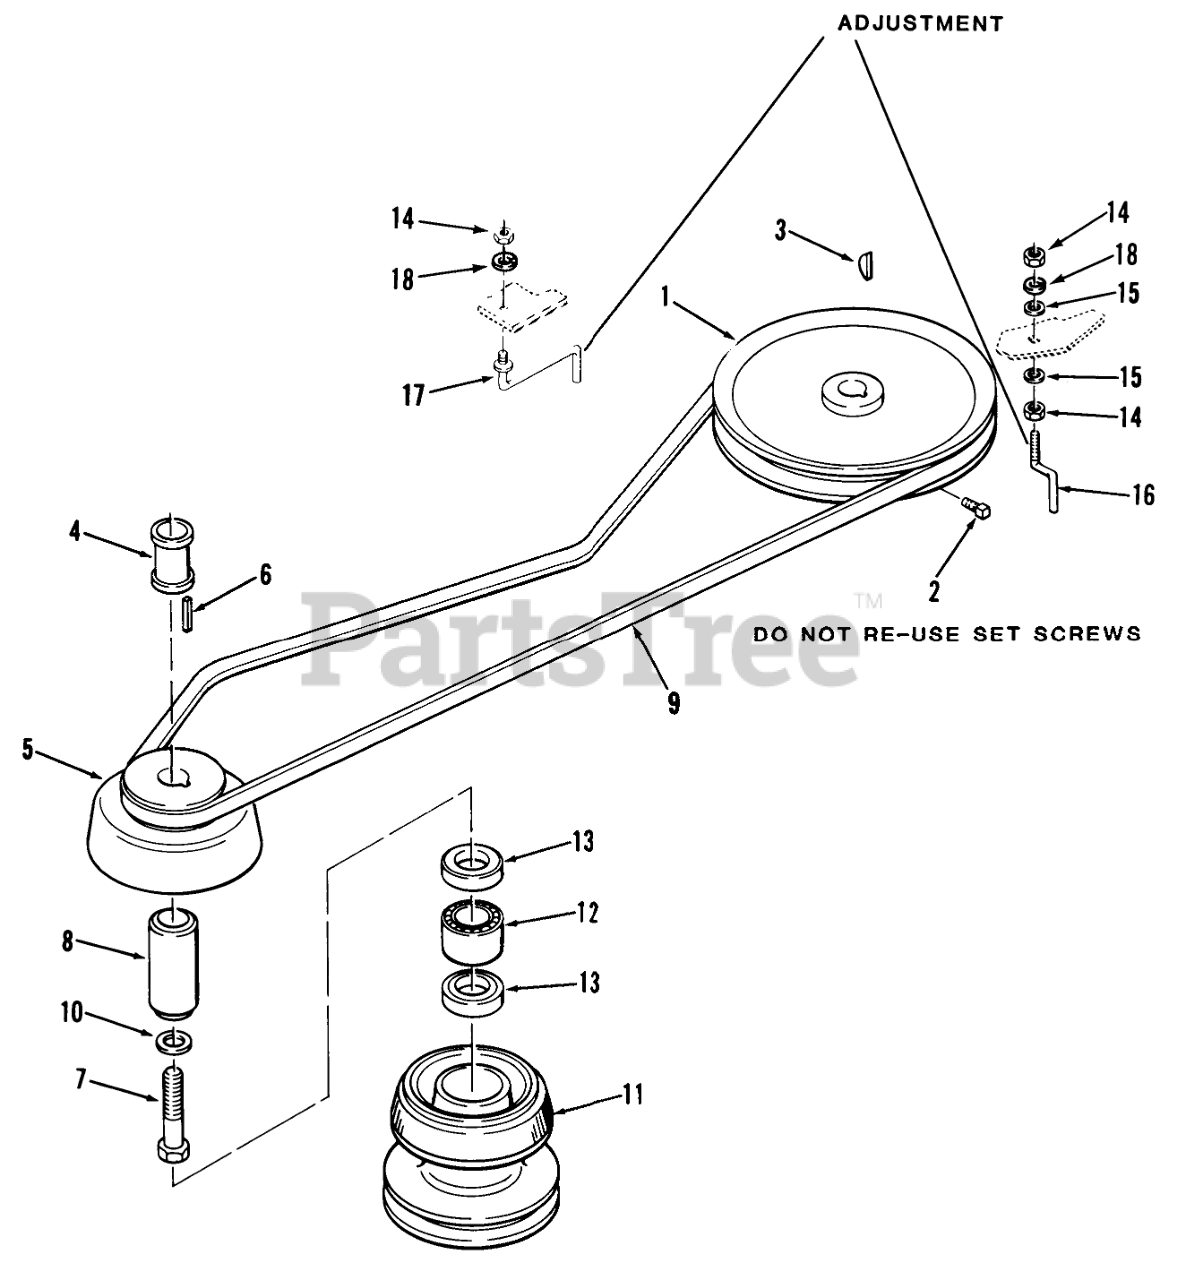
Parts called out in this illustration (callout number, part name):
1	PULLEY-TRANSMISSION
2	Set Screw
3	KEY-HI-PRO
4	TUBE SPACER
5	PULLEY-ENGINE
7	HEX HD CAP SCREW
8	RACE BEARING
9	V-BELT
10	WASHER
11	Assy Pulley Mwr Dr
12	BRG-NEEDLE OPEN END
13	SEAL-OIL
14	Nut
15	WASHER 5/16 SAE
16	GUIDE-BELT
17	GUIDE-BELT
18	Lockwasher
